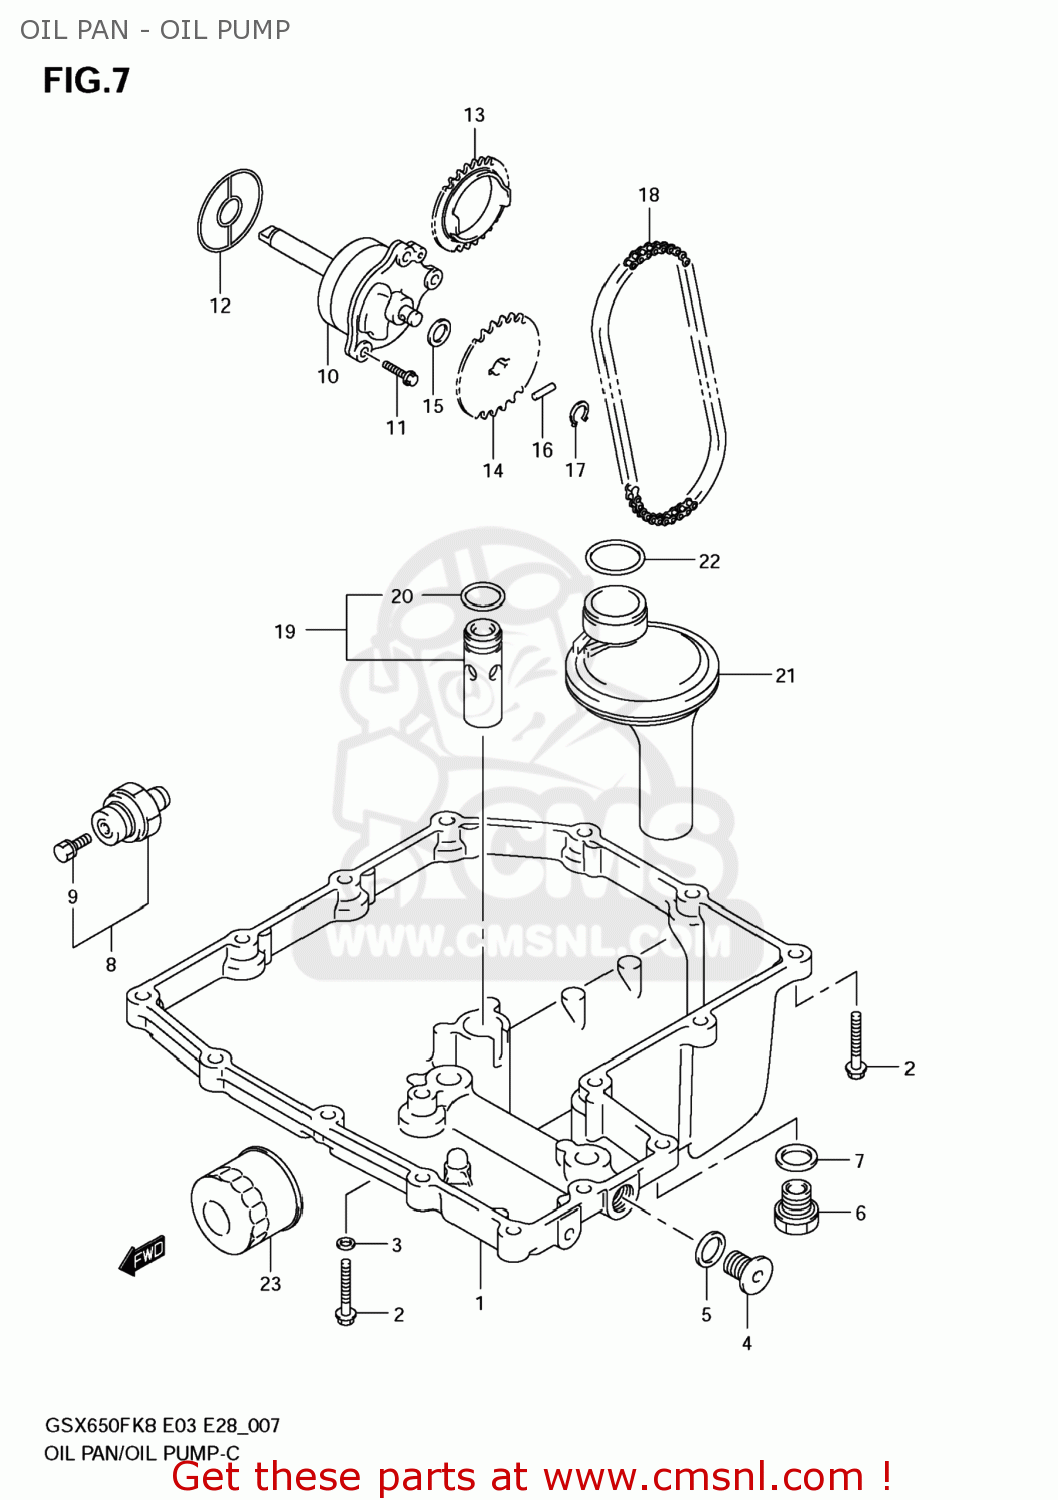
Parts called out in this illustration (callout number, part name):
1	PAN,OIL
2	BOLT
3	GASKET(5.8X13X1.2) (NAS)
4	PLUG(L:12)
5	GASKET(12.1X16.2X3.7) (NAS)
6	PLUG(14X20)
7	GASKET(13.8X18.8X4.8) (NAS)
8	SWITCH ASSY,OIL PRESSURE
9	BOLT,OIL PRESSURE SWITCH
10	PUMP ASSY,ENGINE OIL
11	BOLT
12	O RING,OIL PUMP
13	SPROCKET,OIL PUMP DRIVE
14	SPROCKET,OIL PUMP DRIVEN
15	SHIM(10X18X0.5)
16	PIN(4X15.8)
17	CIRCLIP
18	CHAIN,OIL PUMP DRIVE
19	VALVE ASSY,OIL RELIEF(7K)
20	O RING(D:1.9,ID:13)
21	STRAINER ASSY,ENGINE OIL
22	O RING(D:2.4,ID:24.7)
23	FILTER ASSY,EN
